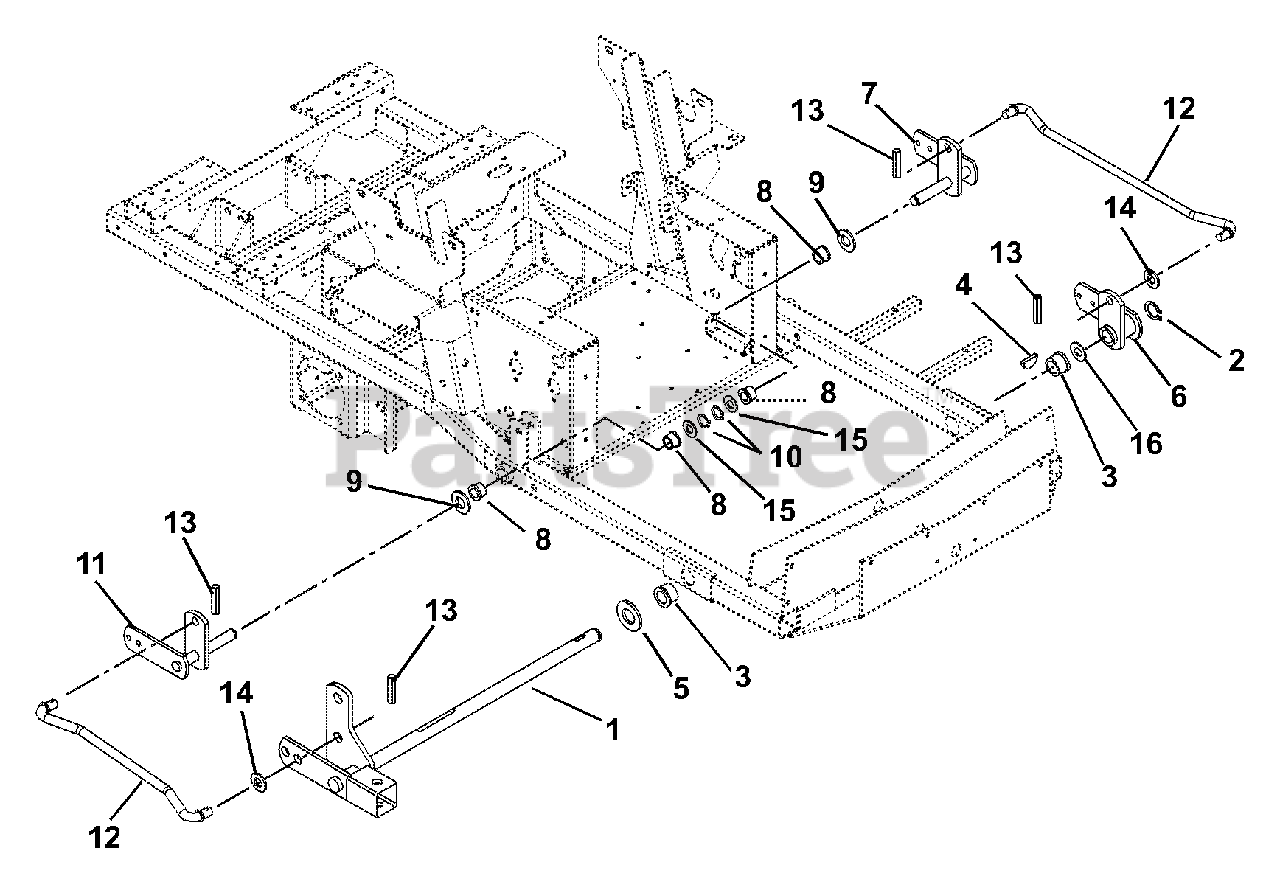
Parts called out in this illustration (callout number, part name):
1	MOWER LIFT
2	RG-RTNG-EXT 1.00X.078
3	BSHG-FLG1.020X1.385X.75X1.75NY
4	KEY-WDRF .25X1.00 HRD #15
5	WSHR-FL-STL 1.063X2.00X.134
6	WMT, FRONT MOWER LIFT-LH
7	WMT, REAR LIFT ARM -LH
8	BSHG-FLG .762X1.0X.580X1.48 NY
9	WSHR-HDND-THRST .758X1.23X.031
10	RG-RTNG-EXT .689X.078
11	WMT, REAR LIFT ARM - RH
12	ROD, LIFT ASSIST 19.35"
13	PIN-ROLL .250X1.25 STNLESS STL
14	WSHR-FL-STL .630X1.250X.062 YZ
15	WSHR-FL-STL .755X1.25X.125 YZ
16	WSHR-HDND-THRUST 1.00X1.55X.03
